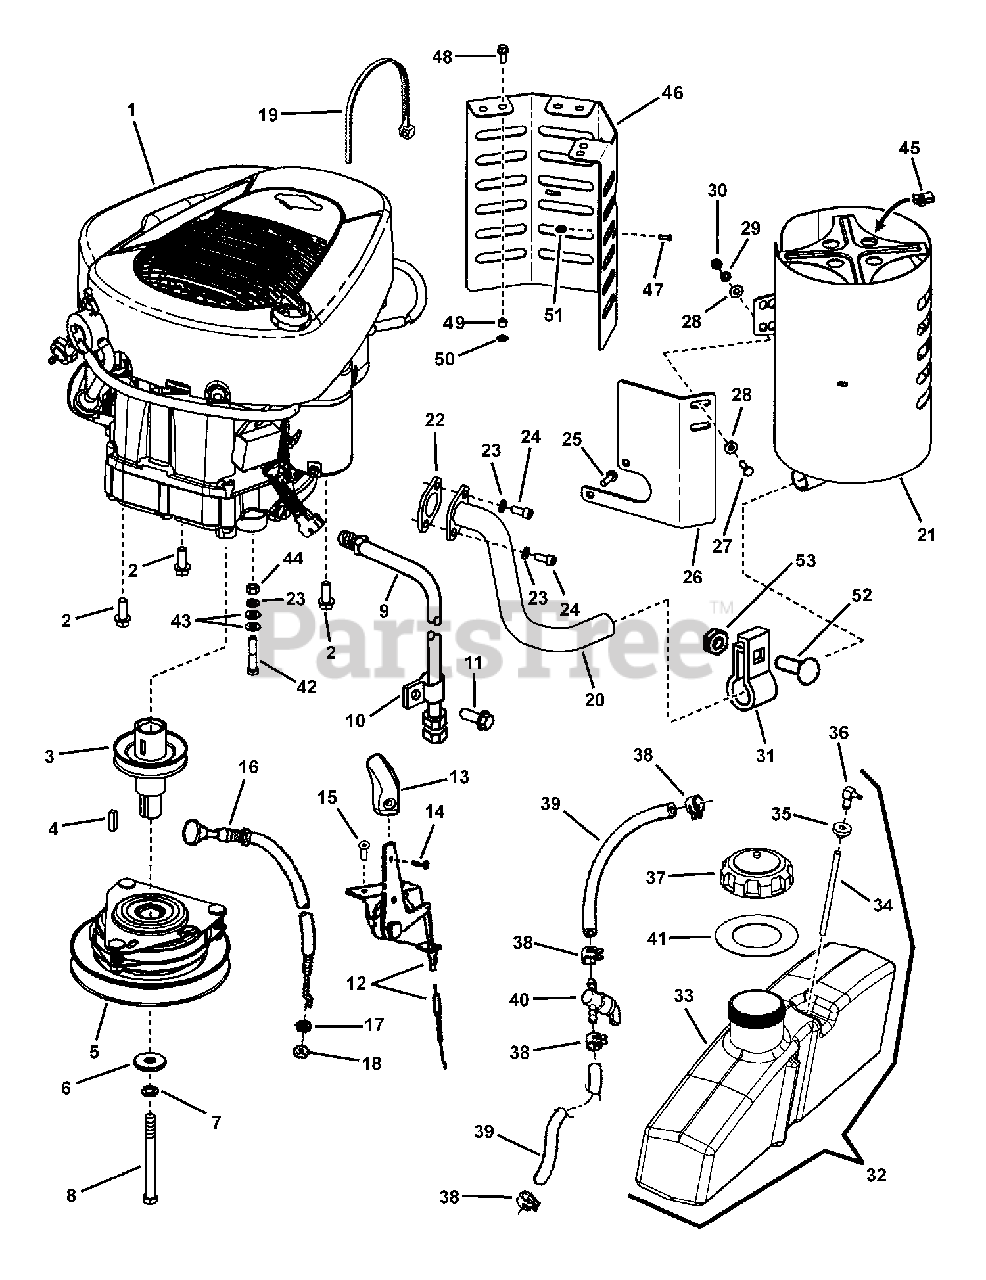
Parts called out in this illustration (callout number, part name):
1	* ENGINE, 18.5 HP B&S Intek Mod. 31P777-0122-B1, Euro RZT
2	SCREW, 3/8-16 x 1" Hex Washer Self-Tap
3	ASSEMBLY, Engine Pulley
4	KEY, 1/4 Square x 1"
5	CLUTCH, Ogura JD-11
6	WASHER, .468 ID x 1.50 OD x .188 Flat
7	WASHER, 7/16" Split Lock
8	SCREW, 7/16-20 x 4-1/2" Hex Head Cap, GR 5
9	HOSE, Oil Drain
10	HARNESS CLIP, 5/8"
11	SCREW, 5/16-18 x 5/8" Hex Washer Self-Tap, GR 2
12	CABLE, 26.25" Throttle Control
13	KNOB, Throttle, Red RZT
14	SCREW, #10-16 x 3/4" Pan Head Self-Tap
15	SCREW, 1/4-20 x 5/8" Pan Head Self-Tap (Torx)
16	CABLE, 30" Choke Control
17	WASHER, 3/8" Internal Tooth Lock
18	NUT, 3/8-24 Hex, GR B
19	CABLE TIE, 7"
20	MANIFOLD, 18 HP B&S Intek
21	** MUFFLER, LC YZ
21	MUFFLER, RZT
22	GASKET, Exhaust
23	WASHER, 5/16" Split Lock
24	SET SCREW, 5/16-18 x 3/4" Socket Head, GR 8
25	SCREW, 1/4-20 x 3/4" Hex Washer Self-Tap
26	BRACKET, Muffler 18HP Briggs
27	SCREW, 1/4-20 x 3/4" Hex Head Cap, GR 5
28	WASHER, .28 x .63 x .06 Flat, GR 5
29	WASHER, 1/4" Split Lock
30	NUT, 1/4-20 Hex, GR 5 or B
31	CLAMP, Muffler
32	ASSEMBLY, Fuel Tank, RZT
33	FUEL TANK
34	DIP TUBE
35	GROMMET
36	ELBOW, 90 Degree
37	CAP, Fuel, 3-1/2"
38	CLAMP, Fuel Line
39	HOSE, Fuel, 5"
40	VALVE, Fuel Shut-Off
41	SEAL, Tank
42	SCREW, 5/16-18 x 1-3/4" Hex Head Cap, GR 5, YZ
43	WASHER, .34 x .69 x .08 Flat
44	NUT, 5/16-18 Hex, GR 5 or B
45	SPEED NUT, 1/4-20 U Type/070/.140 Black
46	HEAT SHIELD, Muffler, ERZT, MY06
47	SCREW, #8-32 x 1/2" Cross Recess Pan Head
48	SCREW, 1/4-20 x 5/8" Hex Flange Lock
49	BUSHING, .250 ID x .375 OD x .25 Long
50	RETAINER, 1/4" Bolt
51	PUSH NUT
52	BOLT, 5/16-18 x 1-1/4" Square Neck Carriage
53	NUT, 5/16-18 Hex Flange Lock, GR 5
